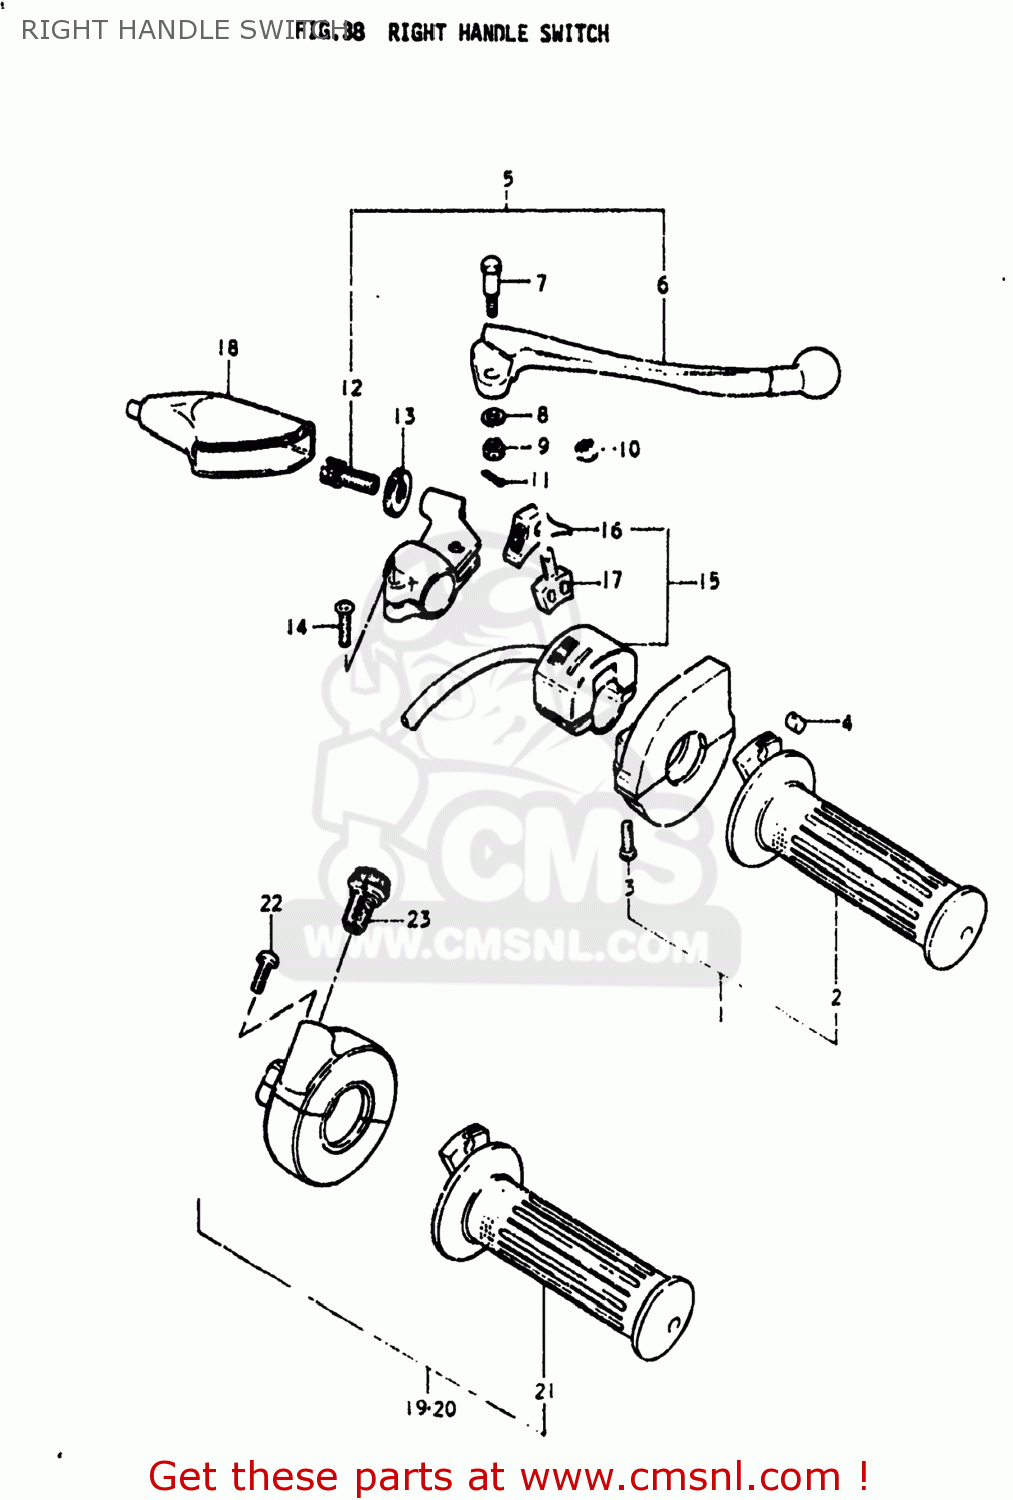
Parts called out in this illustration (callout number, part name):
1	GRIP ASSY,THROTTLE
2	GRIP,THROTTLE
3	SCREW
4	PIECE,THROTTLE END
5	LEVER ASSY,BRAKE
6	LEVER,BRAKE
7	BOLT,LEVER
8	LOCK WASHER
9	NUT,LEVER FITTNG
10	NUT 6MM
11	COTTER PIN
12	ADJUSTER,CABLE
13	NUT,CABLE ADJUSTER
14	SCREW
15	SWITCH ASSEMBLY,LIGHTING
16	KNOB,HANDLE SWITCH
17	BLOCK,LIGHTING/DIMMER
18	COVER,CLUTCH LEVER
19	GRIP ASSEMBLY,THROTTLE
20	GRIP ASSEMBLY,THROTTLE
21	GRIP,THROTTLE
22	SCREW
